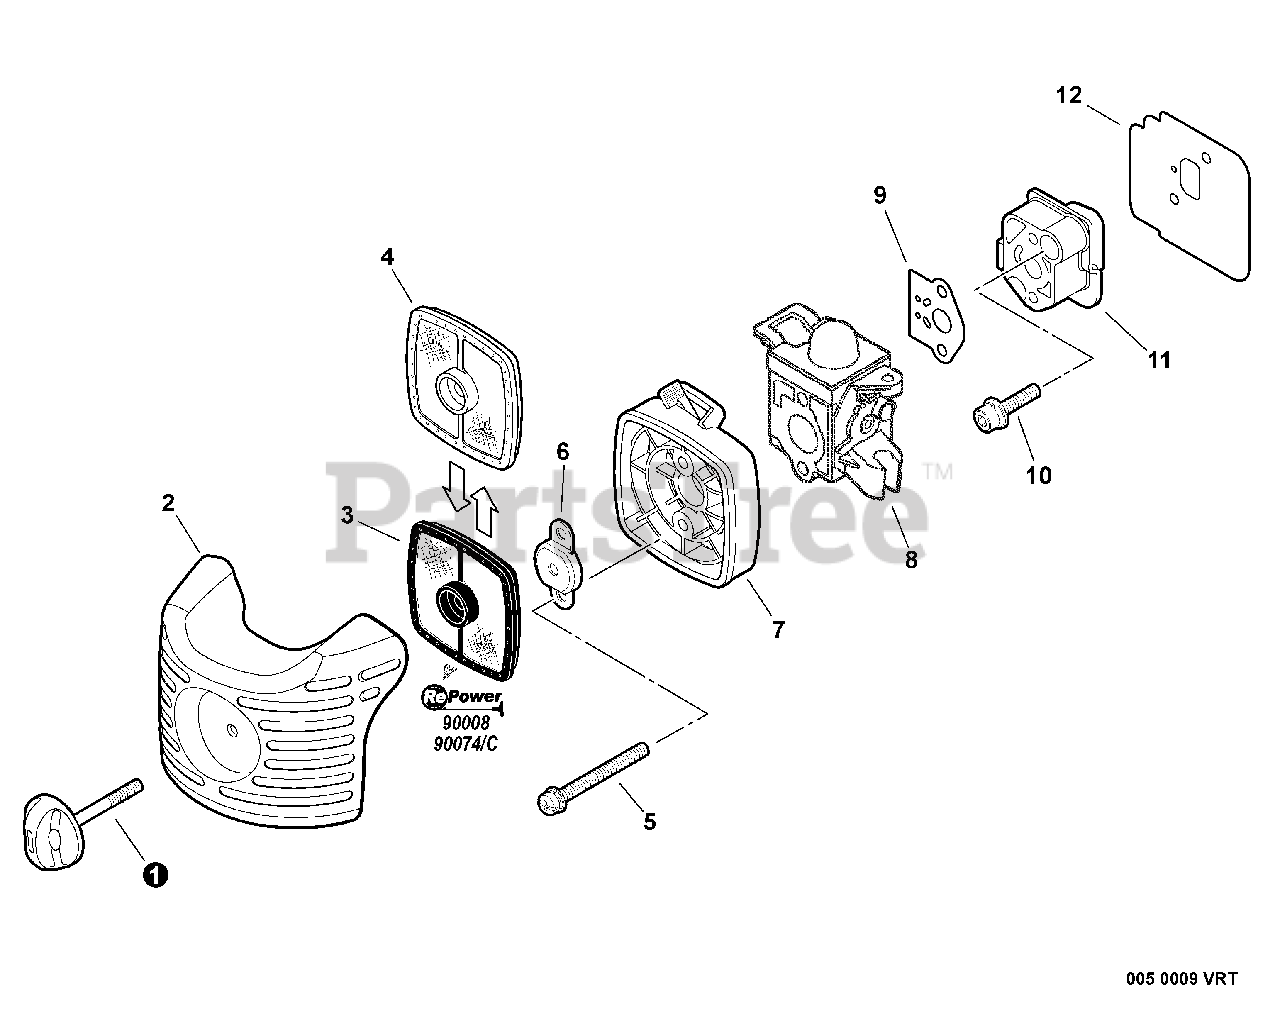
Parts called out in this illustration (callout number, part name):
1	THUMBSCREW
2	COVER, AIR FILTER
3	FILTER, AIR - DOUBLE LAYER
4	FILTER, AIR - SINGLE LAYER
5	SCREW - 5X65
6	PLATE, PREVENT
7	CASE, AIR FILTER
8	CARBURETOR
9	GASKET, INTAKE
10	INSULATOR, INTAKE
11	SCREW - 5X25
12	SHIELD, INTAKE
13	RePower TUNE-UP KIT
14	RePower FILTER KIT
